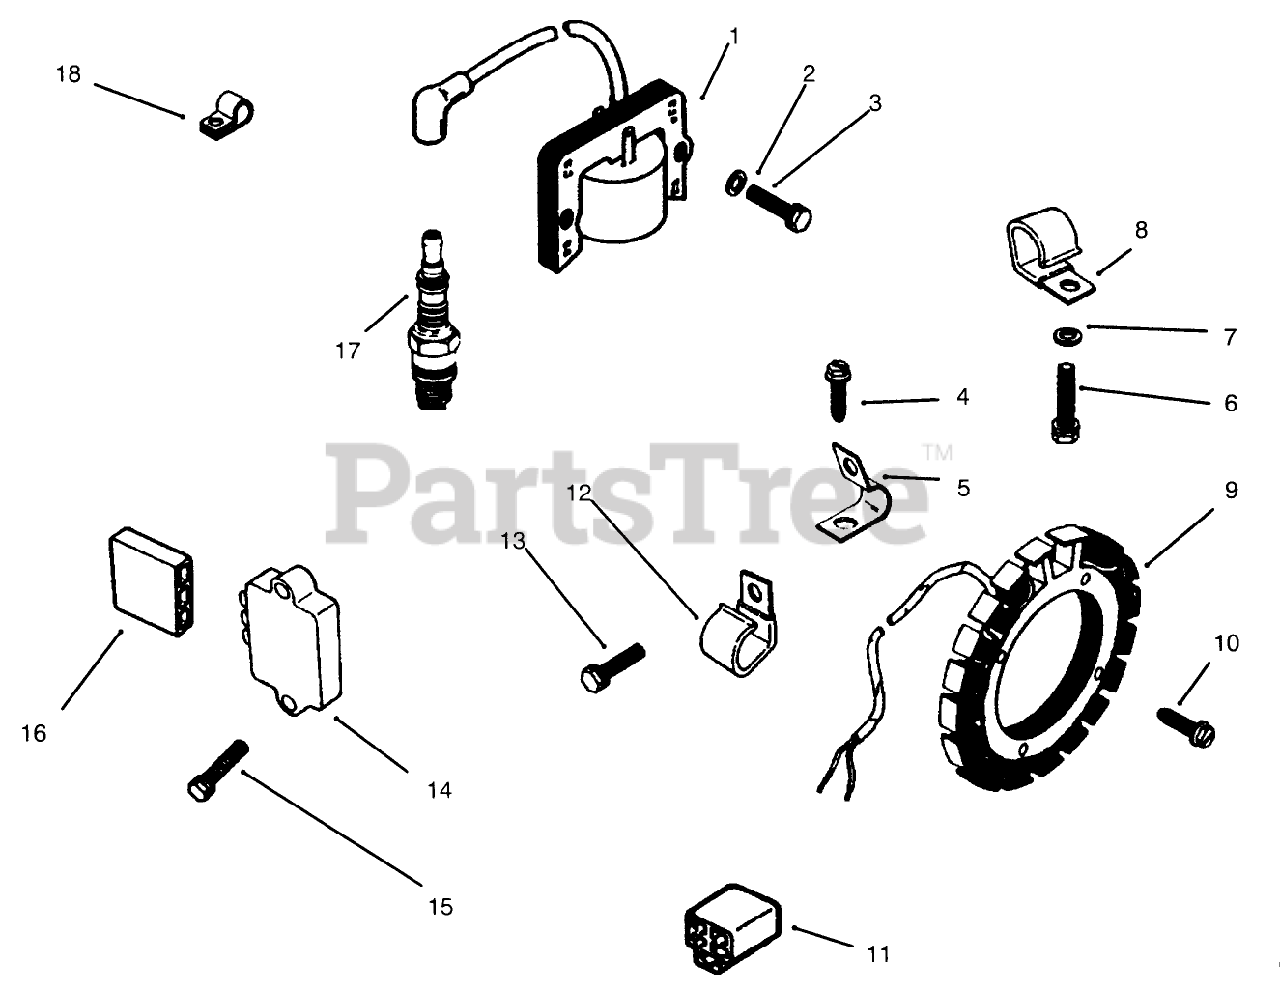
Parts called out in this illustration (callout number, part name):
1	Module-Ignition
2	Washer
3	Screw
4	Screw-Hex Hd
5	Clip
6	Screw
7	Washer
8	Clip
9	Stator
10	Screw
11	Connector
12	CLIP
13	SCREW-HH
14	Kit-Rectifier/Regulator (Incl. Ref. #2)
14	Regulator-Recifier
15	Screw
16	Connector
17	Plug-Spark
18	Clip-Cable
